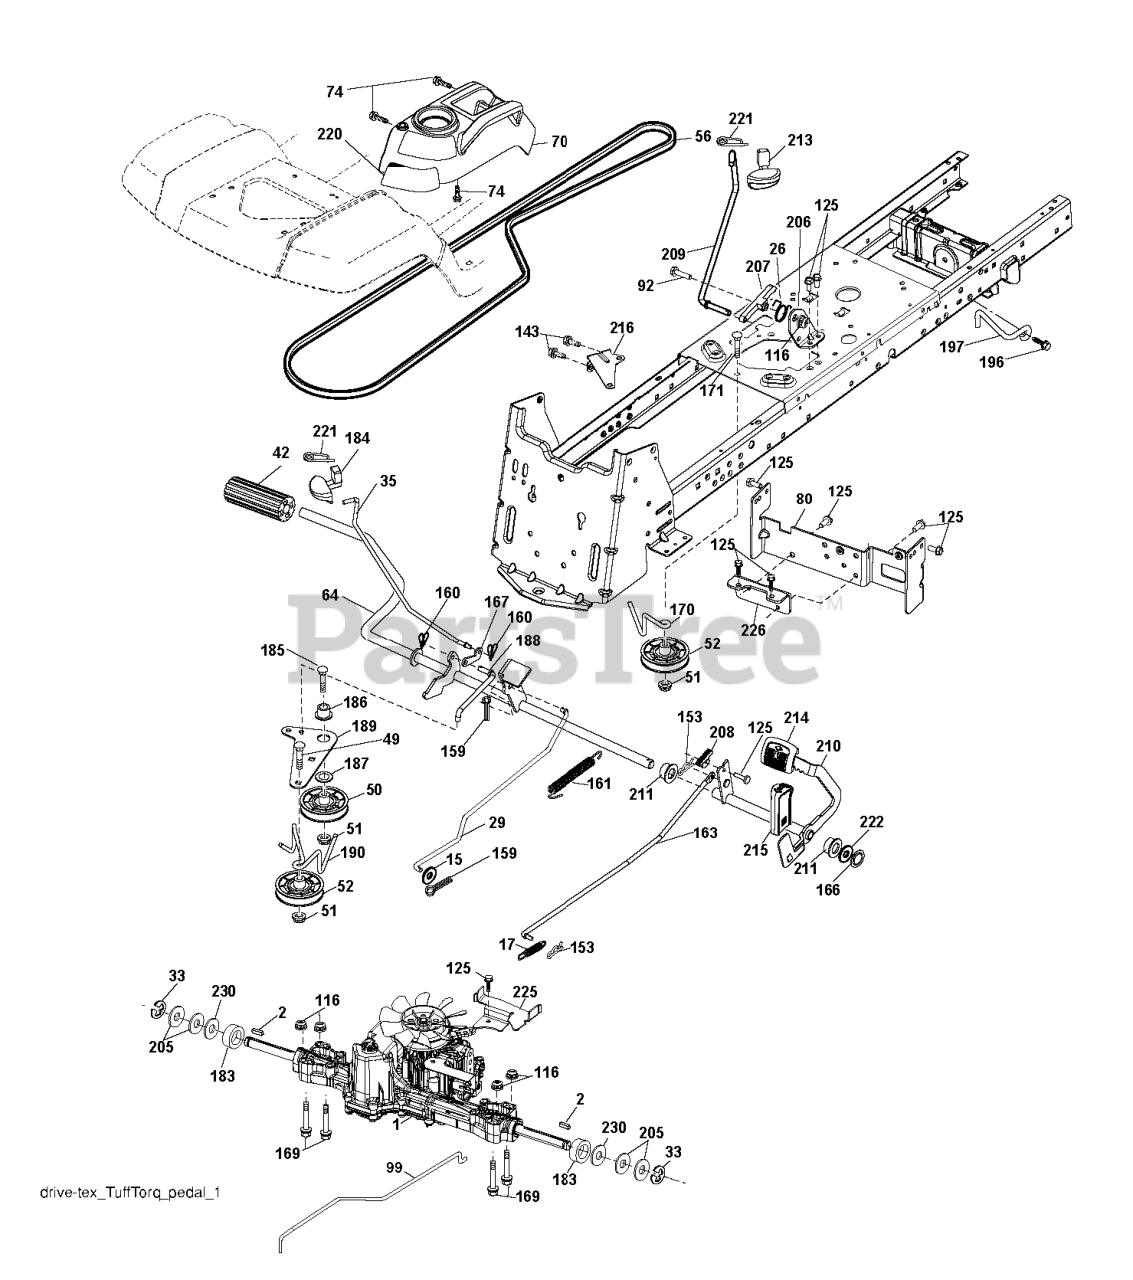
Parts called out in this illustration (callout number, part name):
2	SQUARE KEY
15	WASHER
17	SPRING.BRAKE.K46.GREEN
26	SPRING.RETURN.CRUISE
29	ROD.BRAKE.K46
35	ROD.BRAKE.PARKING.GT.H
42	PEDAL COVER T
50	IDLER.FLAT.910.OFFSET
51	NUT LOCK FLG 3/8-16 UNC
52	IDLER.V-GROOVE.910.OFFSET
56	V-BELT.MOWER.92.40.42/K46
64	SHAFT.ASM.PEDAL.BRK.CNTR
70	RP CONSOLE.ASM.PCH.W/TB
74	SCREW.HI-LO.CONSOLE
80	STRAP TORQUE
92	BOLT
99	ROD.SPRING.BYPASS.K46.LT.Z
116	NUT LOCK HEX FLANGE 5/16-18
125	SCREW
143	Screw 5/16-18 x 1/2 Hex, Self Tapping 5/16-18 x 1/2
153	RETAINER M
159	COTTER PIN
160	RETAINER CLIP
161	SPRING, RETURN LT
163	ROD.CONTROL.PEDAL.K46
166	NUT.PUSH.625.2006
167	LATCH.BRAKE.SPRING
169	BOLT HEX 5/16-18 GR 5
170	KEEPER.V-IDLER.CENTER.
183	SPACER AXLE
184	HANDLE.PARKG.BRK.HUSQ X667
186	SPACER.RETAINER
187	WASHER 12/32X2X10GA
188	RP.LINK.CLUTCH.GROUND.DRIVE
189	BELLCRANK.GROUND.DRIVE.TEX.
190	KEEPER.BELLCRANK.DRIVE
196	SCREW 3/8-16X1
197	LINK.CLUTCH.ANIT-ROTAT
206	BRKT.MOUNT.LATCH.CRUIS
207	LATCH.CONTROL.CRUISE
208	GEAR.SECTOR.CONTROL.CR
209	ROD.CONTROL.CRUISE.GT.
210	ROCKER.ASM.PEDAL.CONTR
211	BEARING.NYLON
213	KNOB.CONTROL.CRUSIE.HU
214	PEDAL.FORWARD.TEX.GT.4
215	PEDAL.REVERSE.TEX.GT.4
216	BRACKET.PULLEY.IDLER.W/TEX
220	REFLECTOR.RH.TEX GT
221	RETAINER.SPRING.CLIP.H
222	WASHER 21/32 X 1-1/4 X 10 GA.
225	KEEPER.BELT.TRANSAXLE.K46
226	BRACKET.MOUNT.TORQUE.K46.TLT
230	WASHER.HARDENED
